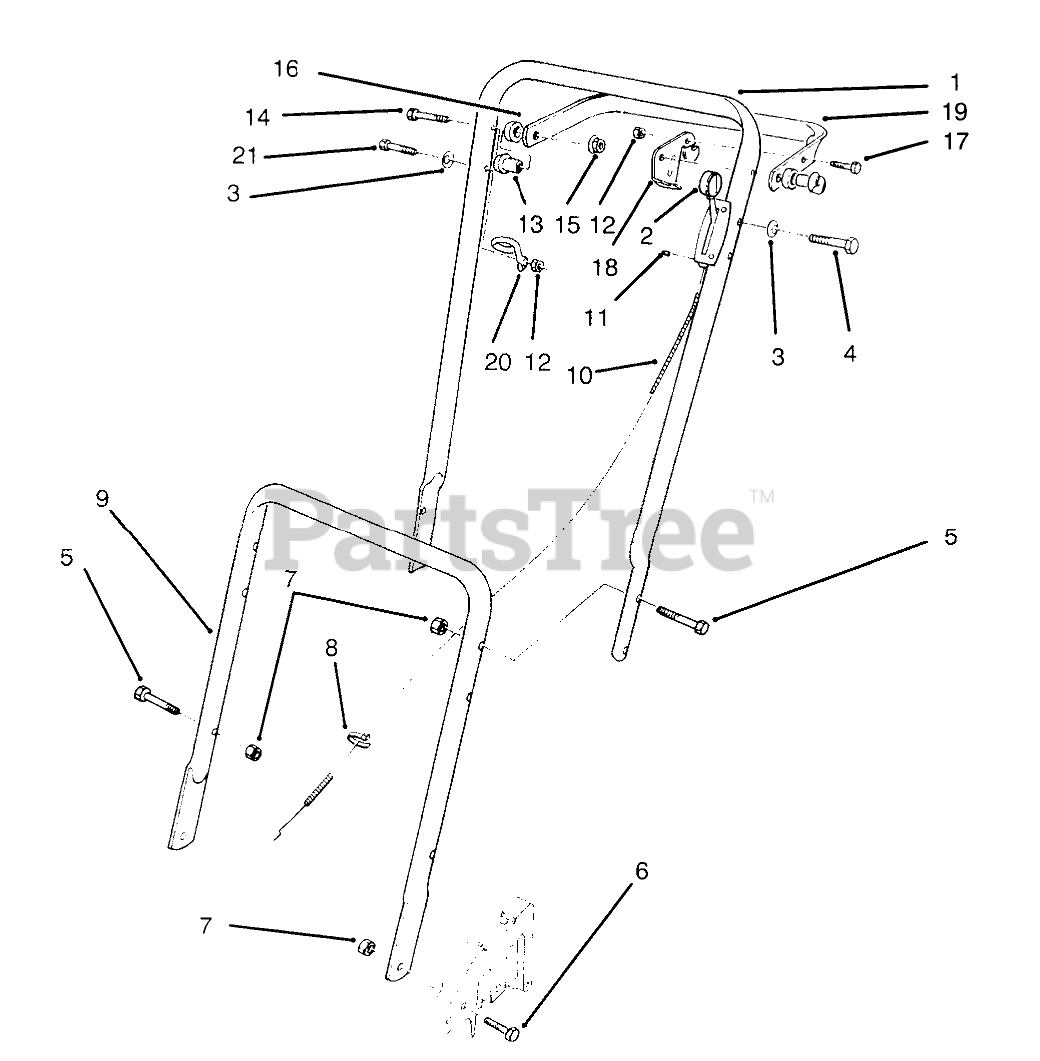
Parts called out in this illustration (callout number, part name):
1	Handle-Upper
2	CONTROL-THROTTLE
3	WASHER
4	SCREW-HH
5	SCREW-HH
6	SCREW-HH
7	NUT-LOCK, NI
8	TIE-CABLE
9	Handle-Lower
10	CABLE-THROTTLE
11	E-RING
12	NUT-LOCK, NI
13	SPACER-SUPPORT
14	SCREW-HH
15	NUT-LOCK, NI
16	SPACER-NYLON
17	SCREW-HH
18	LEVER-CONTROL
19	Bar-Control
20	GUIDE-ROPE
21	SCREW-HH
